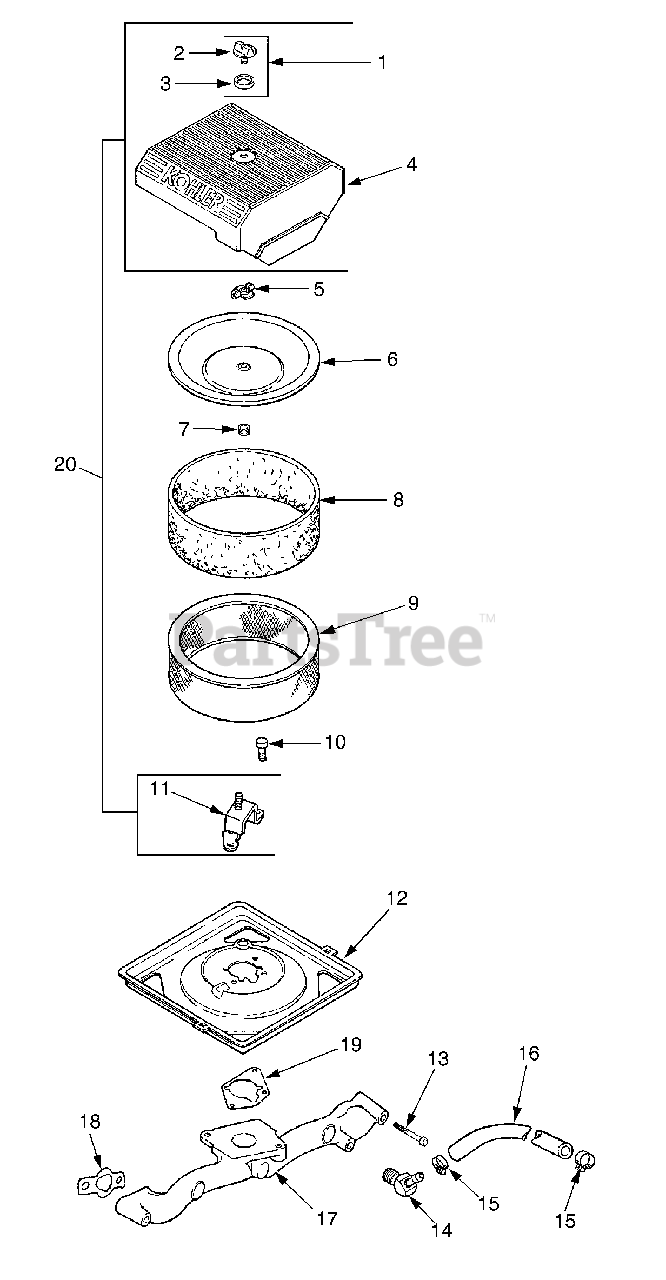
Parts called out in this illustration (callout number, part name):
1	Kit, Knob w/Seal
3	Seal, Air Cleaner Cover Knob
4	Cover, Air Cleaner
6	Cover, Inner Air Cleaner
7	Seal, Inner Air Cleaner
8	Precleaner, Element
9	Element, Air Cleaner
10	Screw, Hex Flange M6 x 1.0 x 16
11	Bracket, Air Cleaner Base
12	Base, Air Cleaner
13	Screw, Hex Flange M6 x 1.0 x 55
14	Connector, Hose 45°.
15	Clamp, Hose
16	Line, Fuel 5"
17	Manifold, Intake
18	Gasket, Intake Manifold
19	Gasket, Air Cleaner Base
20	Kit, Air Cleaner Cover
